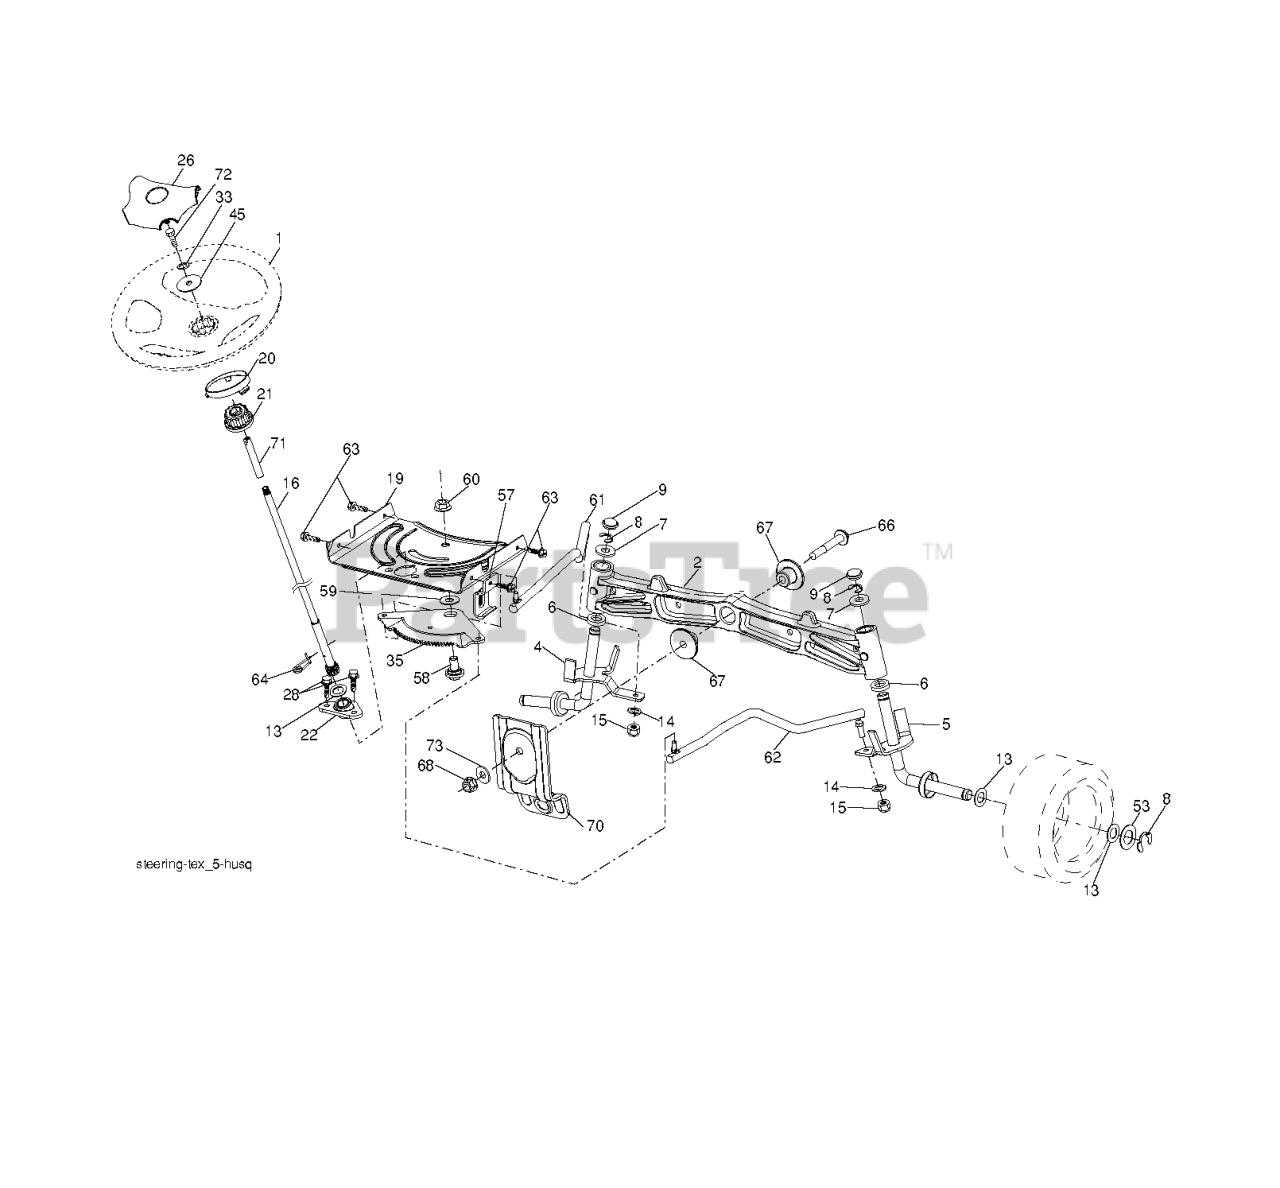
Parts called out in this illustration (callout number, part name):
1	WHEEL.STEERING.LEGEND2.GRY
2	AXLE.HALF.ASM.WELDED
4	SPINDLE.WELDED.LH.15"TEX
5	SPINDLE.WELDED.RH.15"T
6	THRUST WASHER
9	CAP.SPINDLE.BLACK
14	WASHER, LOCK 3/8
15	NUT CROWNLOCK 3/8-24
16	SHAFT STEERING
19	PLATE.STEER.DDL.NLT/NG
20	BOOT, STEERING
21	ADAPTER, WHEEL STNG..
22	BUSHING.ASM.STEERING.A
26	INSERT.CAP.STRG.WH.GRAY
28	SCREW, 3/8-16X3/4
33	WASHER.LOCK.HVY.HLCL.SPR.5/16
35	GEAR.SECTOR.PLATE.DDL.
45	WASHER.11/32
53	WASHER.HARDENED
57	BRACKET.UPSTOP.TEX
58	BOLT.SHOULDER.SECTOR.P
59	WASHER.THURST.SECTOR.S
60	NUT FLANGE LOCK 5/8-11
61	DRAGLINK.LH.BALLSTUD.D
62	DRAGLINK.RH.BALLSTUD.D
63	SCREW
64	RETAINER.CLIP.SPRING.S
66	BOLT HEX FGHD 7/16-14 X 3 SERR
67	BUSHING.PM.FRONT AXLE
68	NUT.LOCK.FLANGE.7/16
70	BRKT.DECK.SUSPENSION.F
71	SHAFT EXTENSION STEERING
72	BOLT YT
73	WASHER.1.5X.505X.118
